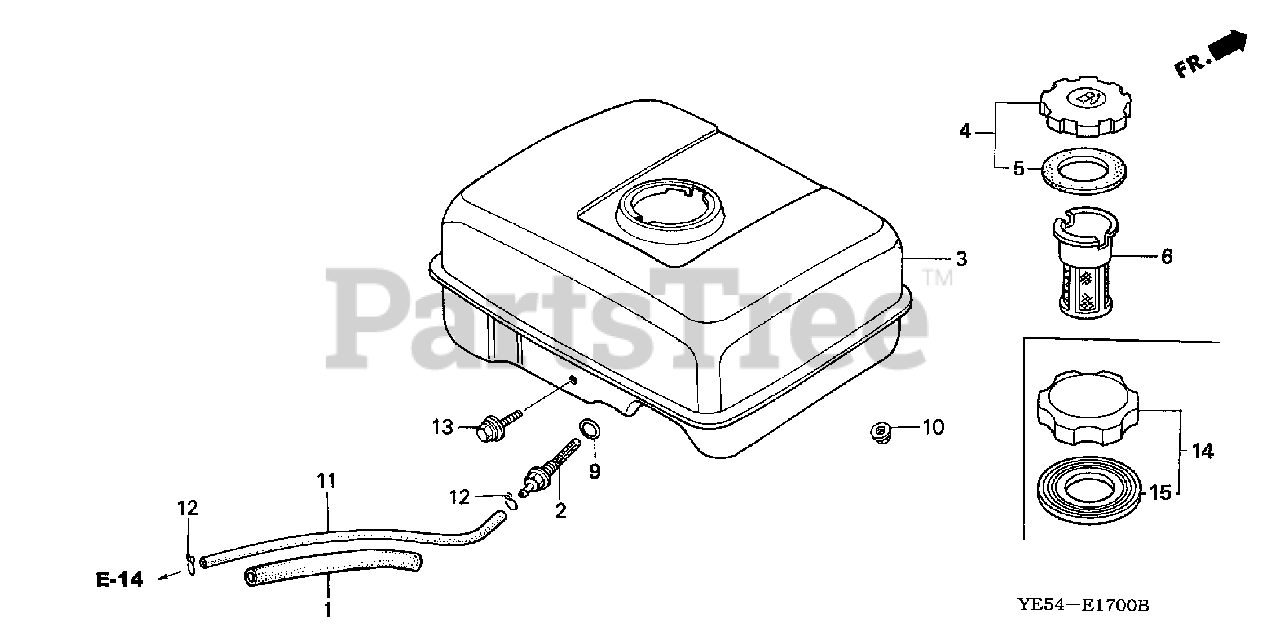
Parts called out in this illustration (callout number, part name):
1	RUBBER, SUPPORTER (107MM)
2	JOINT, FUEL TANK
3	TANK, FUEL *NH31* (MCKINLEY WHITE)
4	CAP, FUEL FILLER
5	GASKET, FUEL FILLER CAP
6	FILTER, FUEL
9	O-RING (13.5X1.5) (ARAI)
10	NUT, FLANGE (6MM)
11	BULK HOSE, FUEL (4.5X3000) (4.5X140)
12	CLIP, TUBE (B8)
13	BOLT, FLANGE (6X29)
14	CAP, FUEL FILLER
15	GASKET, FUEL FILLER CAP
